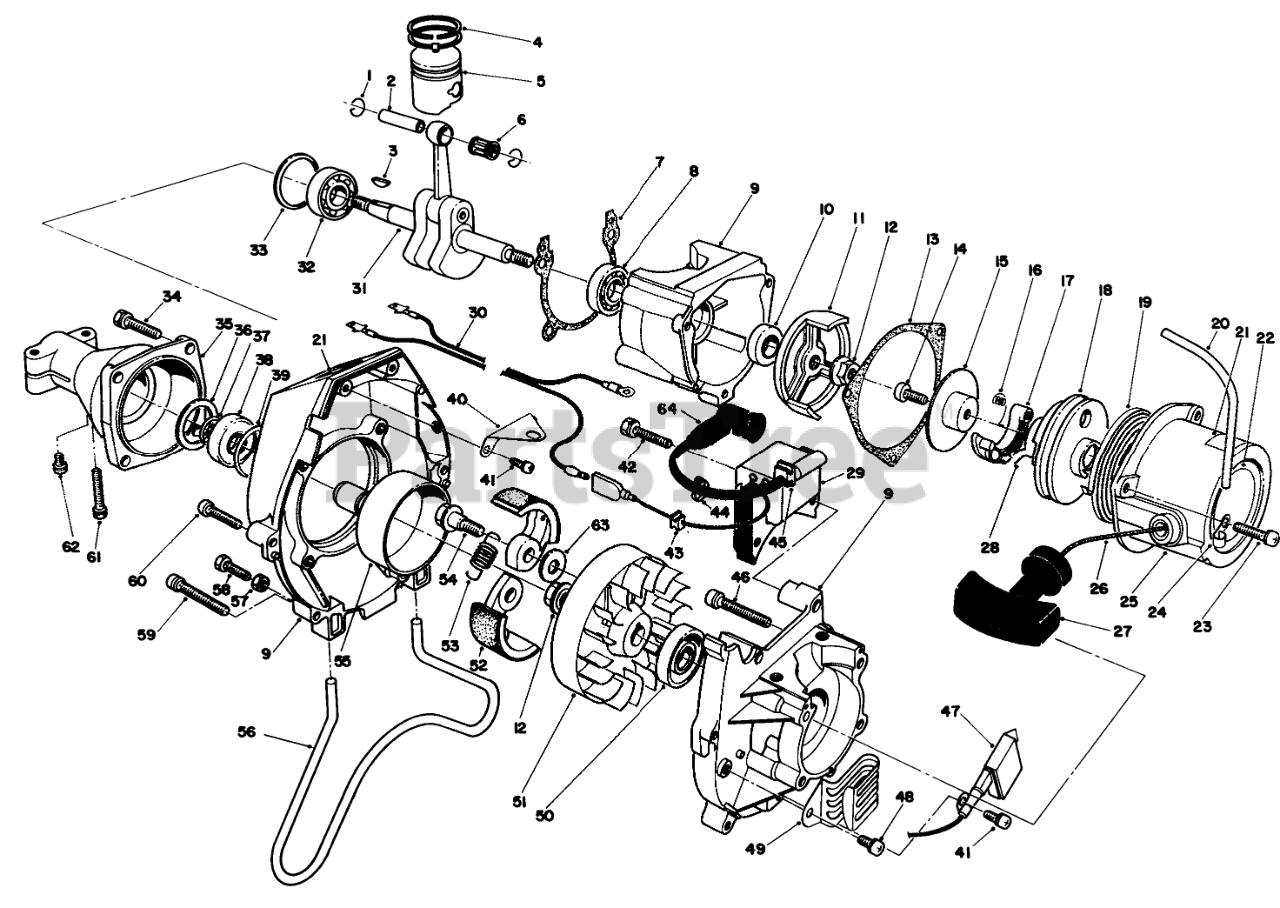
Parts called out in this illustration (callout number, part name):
1	PISTON PIN CLIP
2	PISTON PIN
4	PISTON RING
5	Piston Set (Incl. Ref. #2)
6	NEEDLE BEARING
7	Gasket-Case
8	Bearing
9	Crankcase (Incl. Ref. #46 & 60)
10	OIL SEAL
11	PULLEY, STARTER
12	Nut-Conical
13	Gasket-Starter
14	Screw
15	PLATE, FRICTION
16	SPRING, RETURN
17	RATCHET
19	SPRING, SPIRAL
20	PIPE, OVERFLOW
21	DECAL HOT
22	Decal
23	Screw
24	Clamp
25	Recoil Starter (Incl. Ref. #11, 14-19, 21, 22, & 26-28)
26	Rope-Recoil
27	Knob-Starter
28	SPRING, FRICTION
29	IGNITION COIL
30	WIRE,LEAD
31	Crankshaft (Incl. Ref. #3, &6)
32	BALL BEARING
33	SNAPRING
34	Bolt/Washer
35	Case-Clutch
36	Washer
37	SNAP RING
38	BALL BEARING
39	SNAP RING
40	Bracket
41	SCREW W/ WASHER
42	BOLT AND WASHER
43	Grommet
45	Grommet
46	SCREW & WASHER
47	UNIT,TRANSISTOR
48	Screw & Washer
49	Clamp
50	OIL SEAL
51	Flywheel
52	SHOE, CLUTCH
53	Spring
54	Bolt-Clutch
55	CLUTCH DRUM
56	TANK GUARD
59	Screw
60	Screw
61	BOLT-WASHER/ENG
62	SCREW & WASHER
63	Washer
64	CAP-PLUG
